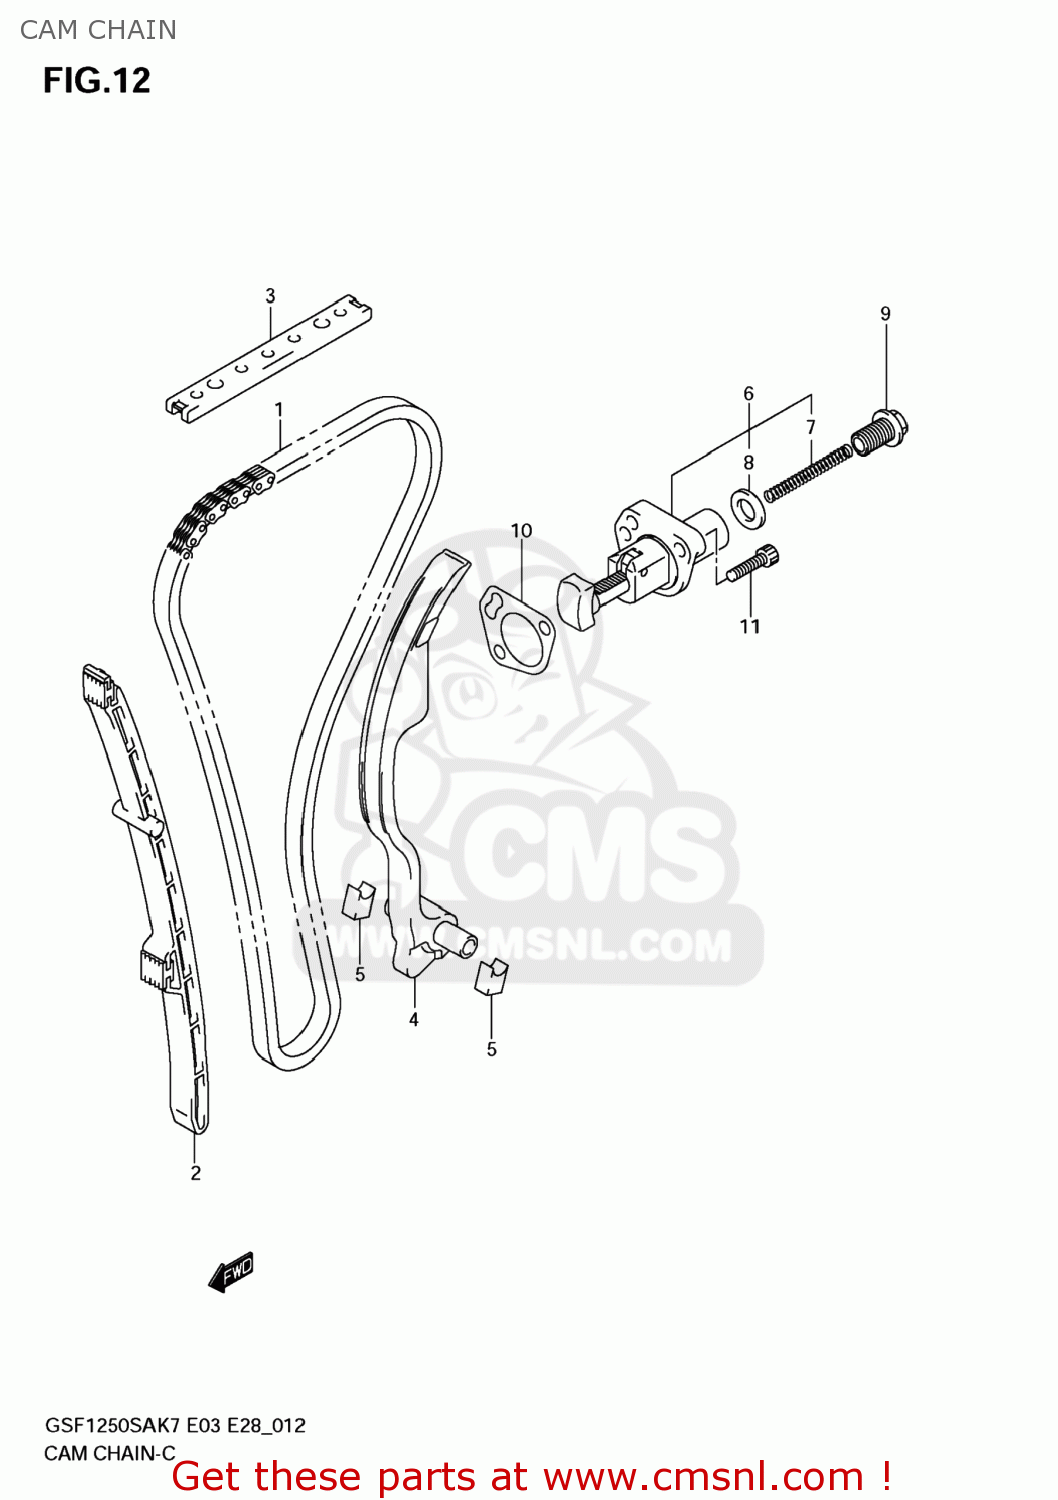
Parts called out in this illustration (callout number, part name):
1	CHAIN,CAMSHAFT DRIVE
2	GUIDE,CAM CHAIN NO.1
3	GUIDE,CAM CHAIN NO.2
4	TENSIONER,CAM CHAIN
5	CUSHION,CAM CHAIN TENSIONER
6	ADJUSTER ASSY,TNSN NO.2 FR
7	SPRING
8	GASKET,TENSIONER ADJUSTER (NAS)
9	PLUG,TENSIONER ADJUSTER
10	GASKET,TENSIONER ADJUSTER (NAS)
11	BOLT
